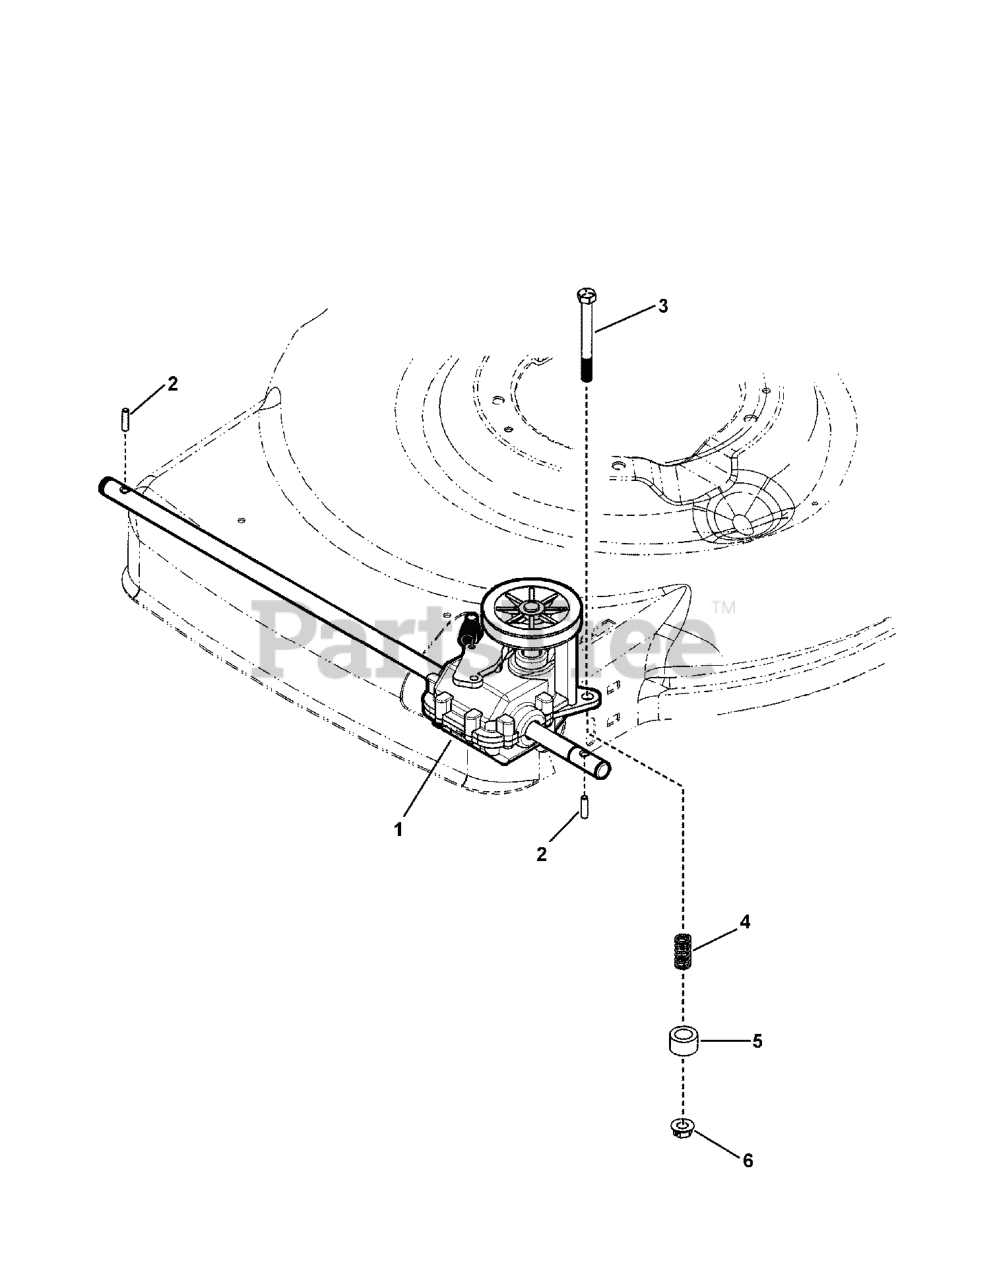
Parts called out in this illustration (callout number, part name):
1	TRANSMISSION, 22" WBM Single Speed, Front Wheel Drive
2	DRIVE PIN, 22" WBM, Front Wheel Drive
3	SCREW, 5/16-18 x 3" Hex Head Cap, P&O
4	SPRING, Compression
5	SPACER, Drive Transmission
6	NUT, 5/16-18 Hex Flange Center Lock, Grade F
